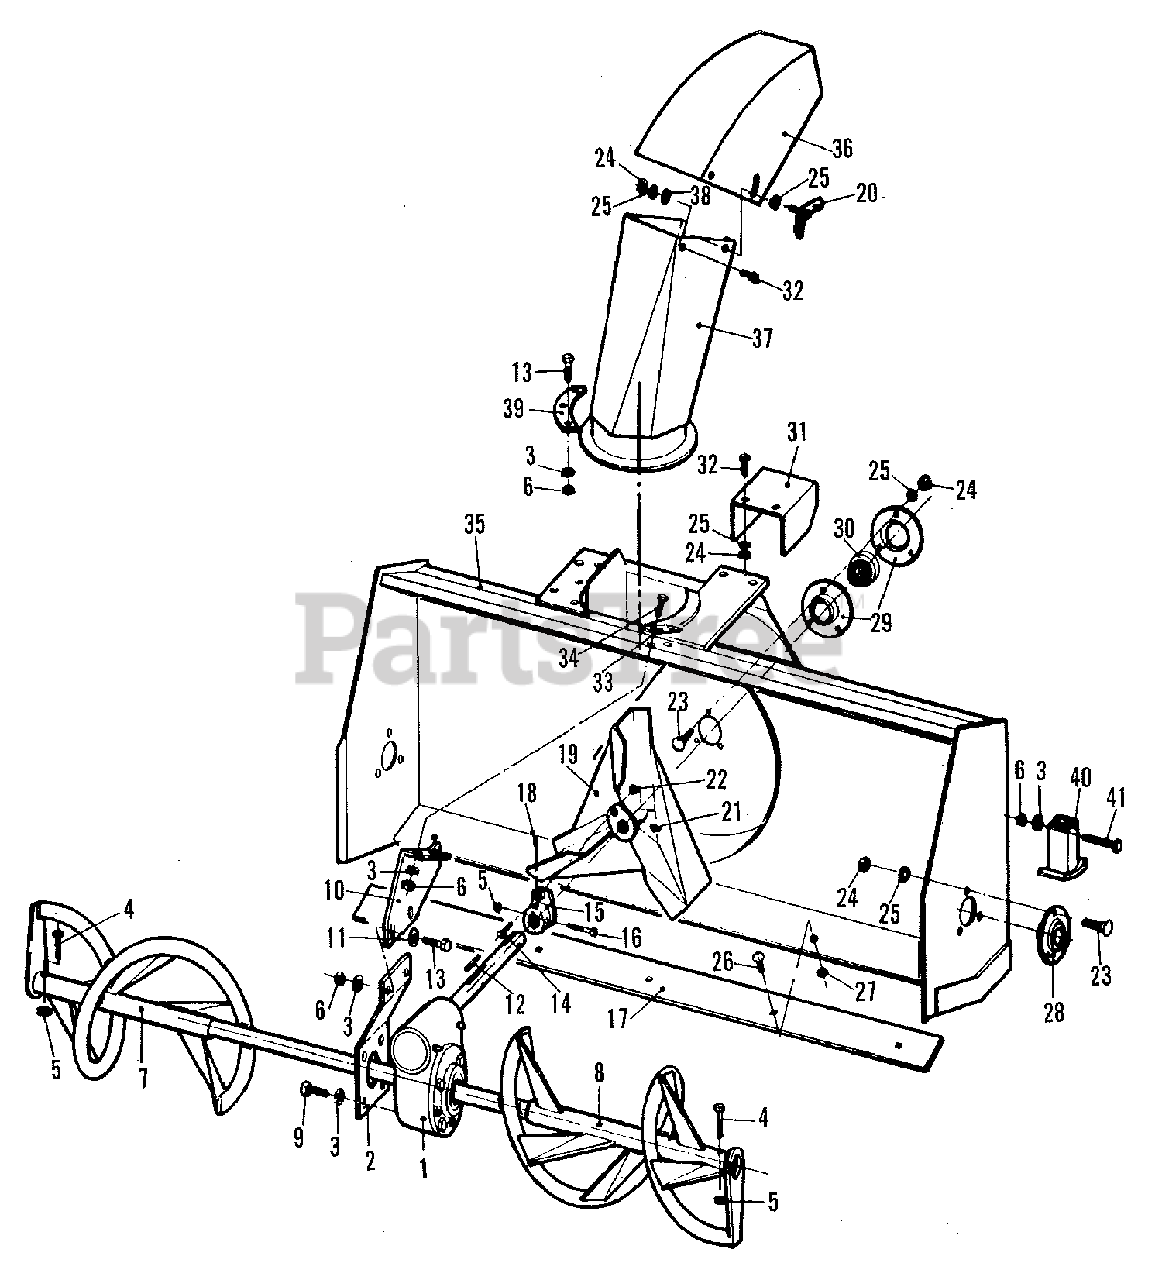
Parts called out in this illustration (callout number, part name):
1	DRIVE ASSEMBLY, Worm 60"
2	BRACKET, Worm Gear Mounting
3	LOCKWASHER, 1/2
4	CAPSCREW, 5/16NC x 2-1/2
5	LOCKNUT, 5/16NC
7	AUGER, 60" L.H.
8	AUGER, 60" R.H.
9	CAPSCREW, 1/2NC x 1
10	BRACKET, Worm Gear Frame Mounting
11	WASHER, 1/2
12	KEY, 1/4 x 1/4 x 1-1/2
13	CAPSCREW, 1/2NC x 1-1/2
14	CAPSCREW, 1/4NC x 2, Gr. 5
15	PLATE, Shear
16	CAPSCREW, 5/16NC x 2-1/2
17	BLADE, Plow
18	SETSCREW, Hex Socket, Cup Point, 3/8NC x 3/4
20	BOLT, Wing, Chute
21	FITTING, Grease, 1/8NPT
22	LOCKNUT, 1/4NC
23	BOLT, Carriage, 3/8NC x 1
25	LOCKWASHER, 3/8
26	BOLT, Carriage, 7/16NC x 1
27	LOCKNUT, 7/16NC
28	BEARING ASSEMBLY, 1-1/4" Pressed Steel, Complete
29	HOUSING, Bearing, 1-1/4" Pressed Steel (2 HALVES Each)
30	BEARING, Insert, 1-1/4"
31	SHIELD, Sheet, P.T.O.
32	CAPSCREW, 3/8NC x 1
33	PLATE, Reinforcement
34	CAPSCREW, 1/2NC x 1-1/4
35	HOUSING, Main
36	DELFECTOR, Chute
37	CHUTE ASSEMBLY, Snow
38	WASHER, 3/8
39	PLATE, Retainer, Chute
41	CAPSCREW, 1/2NC x 3-1/2
